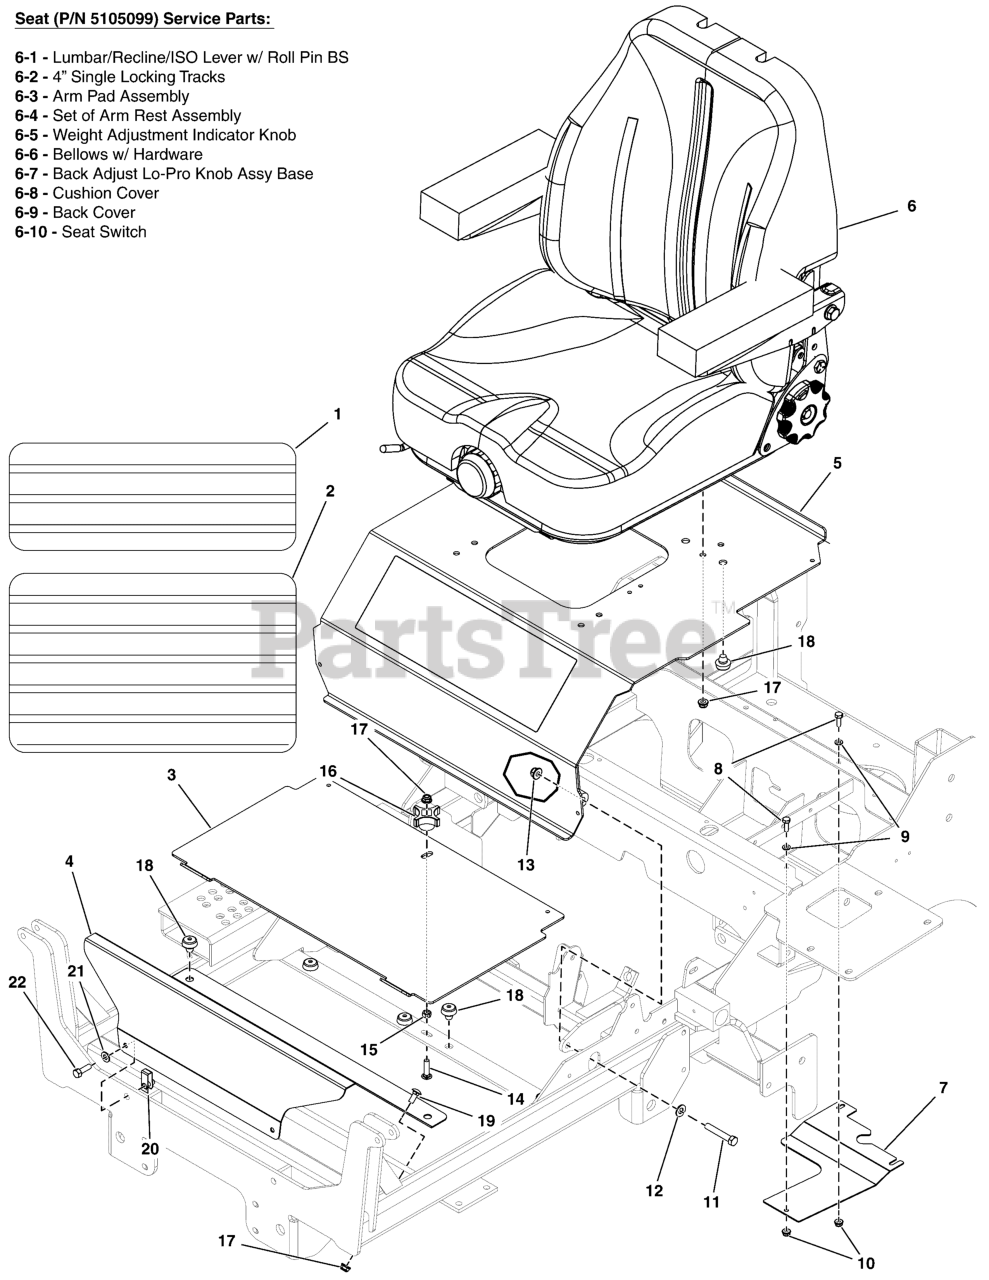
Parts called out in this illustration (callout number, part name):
1	SAFETY WALK, FLOOR REST, 16.00 X 6.00
2	SAFETY WALK, FLOOR PLATE, S50X, 10X17.13
3	PLATE, FLOOR, REMOVABLE, IS3100Z - RED
4	PLATE, FRONT FLOOR, IS3100Z - RED
5	ASSM, SEAT PLATE W/DECALS, IS3200Z-DOM (5412767B)
6	SEAT, HIGH BACK,SEAT'SINC,SUSP, W/SWITCH
6-1	LUMBAR/RECLINE/ISO LVR W/ RLL PIN BS
6-2	4" SINGLE LOCKING TRACKS BASE
6-3	ARM PAD, C13 SEAT
6-4	SET OF ARMREST ASSEMBLY BLK/CHAR CAR FIB/HARBR GRY RED WELT
6-5	WEIGHT ADJUST INDICATOR KNOB ASSY BASE
6-6	BELLOWS W/ HARDWARE BASE
6-7	BACK ADJST LO-PRO KNOB-HRDWR BASE
6-8	CUSHION COVER FOR I3M BLK/CHAR CAR FIB/HARBR GRY RED WELT
6-9	BACK COVER
6-10	SWITCH, SEAT
7	GUARD, DEBRIS, IS2100Z - BLK
8	BOLT, 1/4"-20 X 3/4" GD5 YZ
9	WASHER, 1/4 SAE
10	NUT, 1/4-20 HEX SERR. FLANGE
11	BOLT, 3/8-16 X 2-1/4" GD5 CZ
12	WASHER, 3/8 SAE
13	NUT, 3/8 - 16 HEX NYLOCK FLANGE
14	BOLT, 5/16-18 X 1-1/4, CARRIAGE, GD5, CZ
15	NUT, 5/16-1/8, HEX, CNTR LK, ZINC PHOS/OIL
16	KNOB-INT THR .312-18 4-ARM 2.12WD 1.06LG
17	NUT, 5/16-18 HEX NYLOCK FLANGE NUT
18	MNT, VBRTN, RBBR
19	BOLT, 5/16-18 X 3/4, CARRIAGE, GD5, CZ
20	BODY CLIP, 5/16-18 -1/4 MATERIAL
21	WASHER, 5/16" SAE
22	BOLT, 5/16-18 X 1" GRD5 YZ
